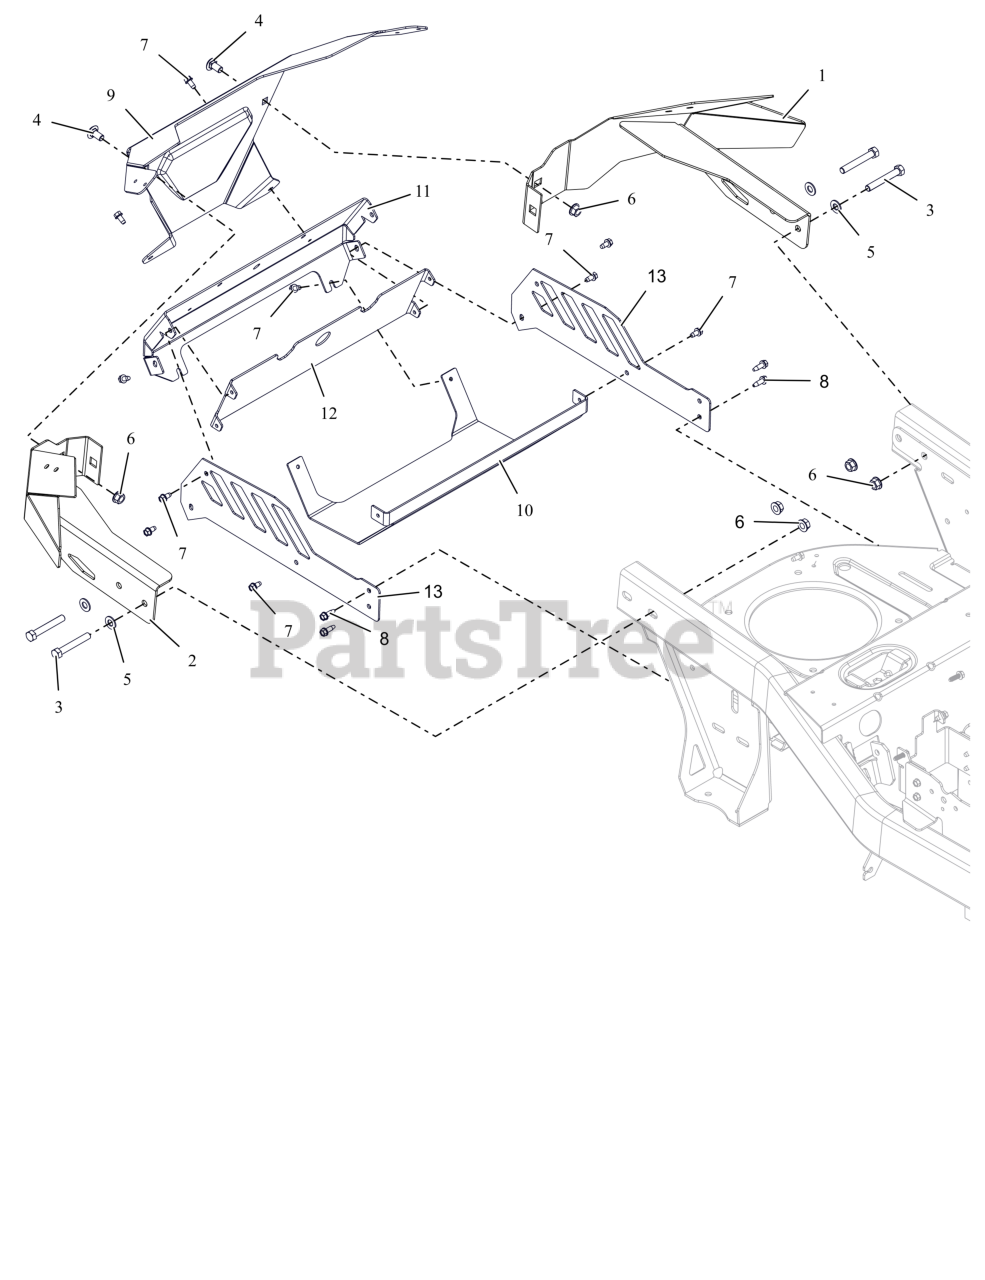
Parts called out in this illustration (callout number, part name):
1	WLDMT, BUMPER -LH (BLACK)
2	WLDMT, BUMPER - RH (BLACK)
3	BLT, HEX .38-16X2.50 G5 ZCC
4	BTL,RHSSN .375-16 X 0.75 G5 FPB
5	WSHR,FLT .406X.812X.065 ZCC
6	NUT-LK-CTR-FLG .375-16 GF ZCC
7	SCR-TAP .25X.50 HWH ZB500
8	SCR, TAP .25-20.X.75 TT2000 ZB500
9	PLATE, BACK WRAP-ARIENS (BLACK)
10	MUFFLER- SHEILD- GRASS BROWN
11	SHIELD- MUFFLER
12	SHIELD- HEAT
13	KIT, MUFFLER SHIELD W/DECALS
